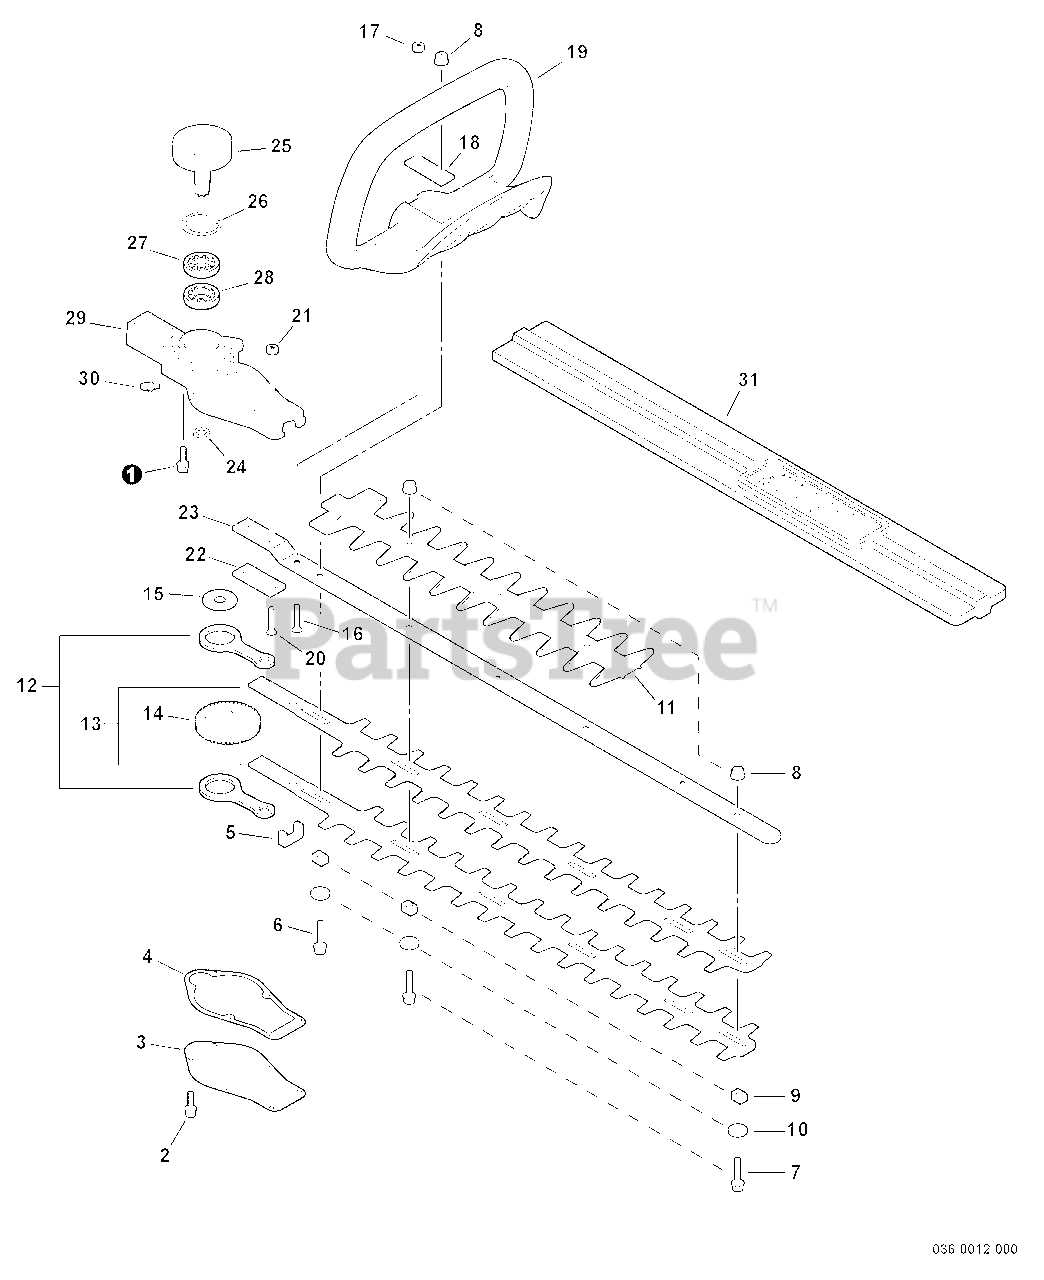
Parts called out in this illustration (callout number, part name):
1	SCREW - 5X20
2	SCREW - 4X10
3	LID, GEAR CASE
4	GASKET, GEAR CASE
5	SEAL, FELT
6	SCREW - 5X40
7	SCREW - 5X20
8	LOCKNUT - 5
9	GUIDE, BLADE
10	WASHER - 6
11	SHIELD, BLADE
12	ROD, CONNECTING
13	BLADE - 20" (50cm)
14	GEAR - DRIVE
16	SCREW - 5X30
17	LOCKNUT - 5
19	HANDLE - FRONT
20	SCREW - 6X25
21	LOCKNUT - 6
23	SUPPORT, BLADE
24	RING, RETAINING - 14
25	DRUM, CLUTCH
26	RING, RETAINING - 35
27	BEARING, BALL - 6202
28	BEARING, BALL - 6202
29	CASE, GEAR
30	FITTING, GREASE
31	COVER, BLADE - 20" (50cm)
